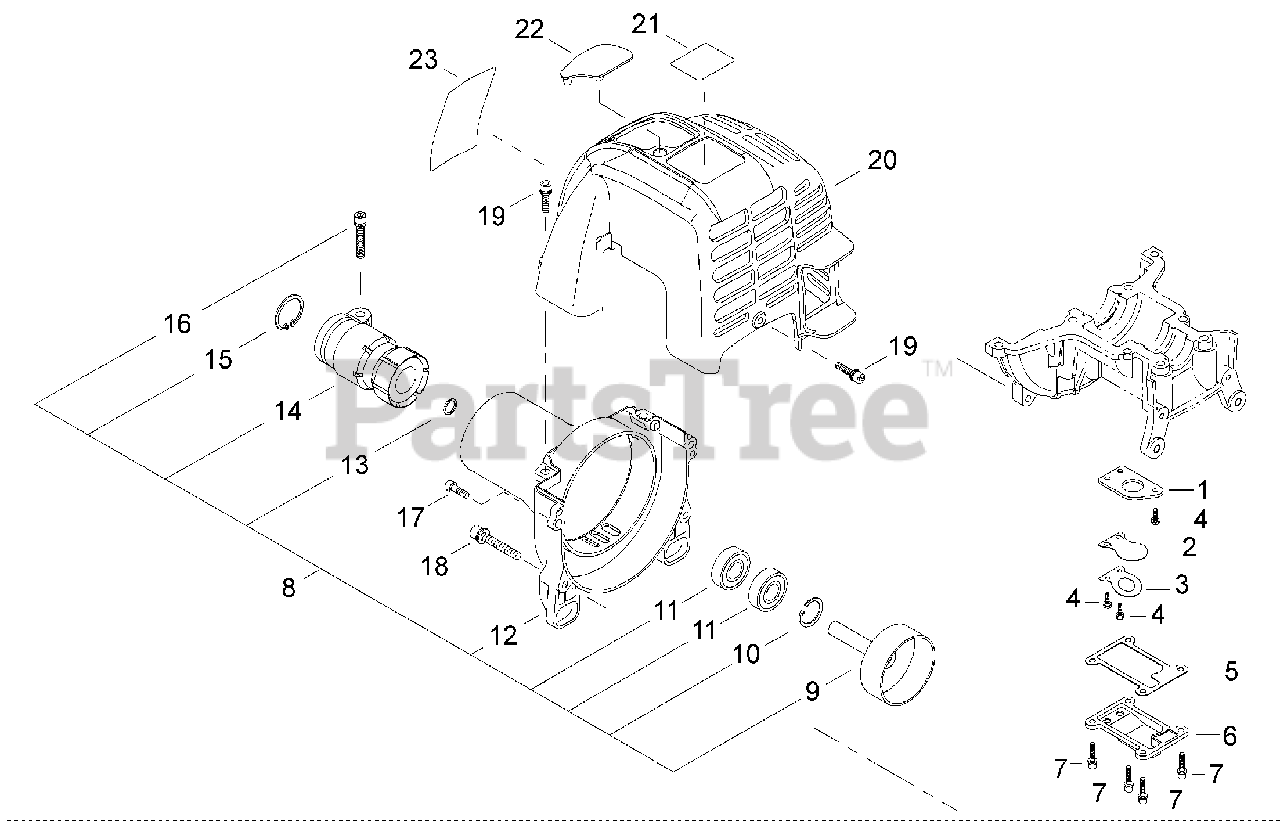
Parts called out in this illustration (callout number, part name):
1	PLATE, REED BACKING
2	VALVE, REED
3	STOP, REED VALVE
4	SCREW - 3X10
5	GASKET, REED VALVE
6	COVER, REED VALVE
7	SCREW - 4X14
8	FAN CASE ASSY
9	DRUM, CLUTCH
10	RING, RETAINING - 28
11	BEARING, BALL - 6001DDUC3
12	CASE, FAN
13	RING, RETAINING
14	CLAMP, MAIN PIPE
15	RING, RETAINING - 42
16	SCREW - 5X22
17	SCREW - 5X16
18	SCREW - 5X40
19	SCREW - 4X14
20	COVER, ENGINE
21	LABEL - MODEL PB-3410
22	COVER, SPARK PLUG
23	LABEL - C4
